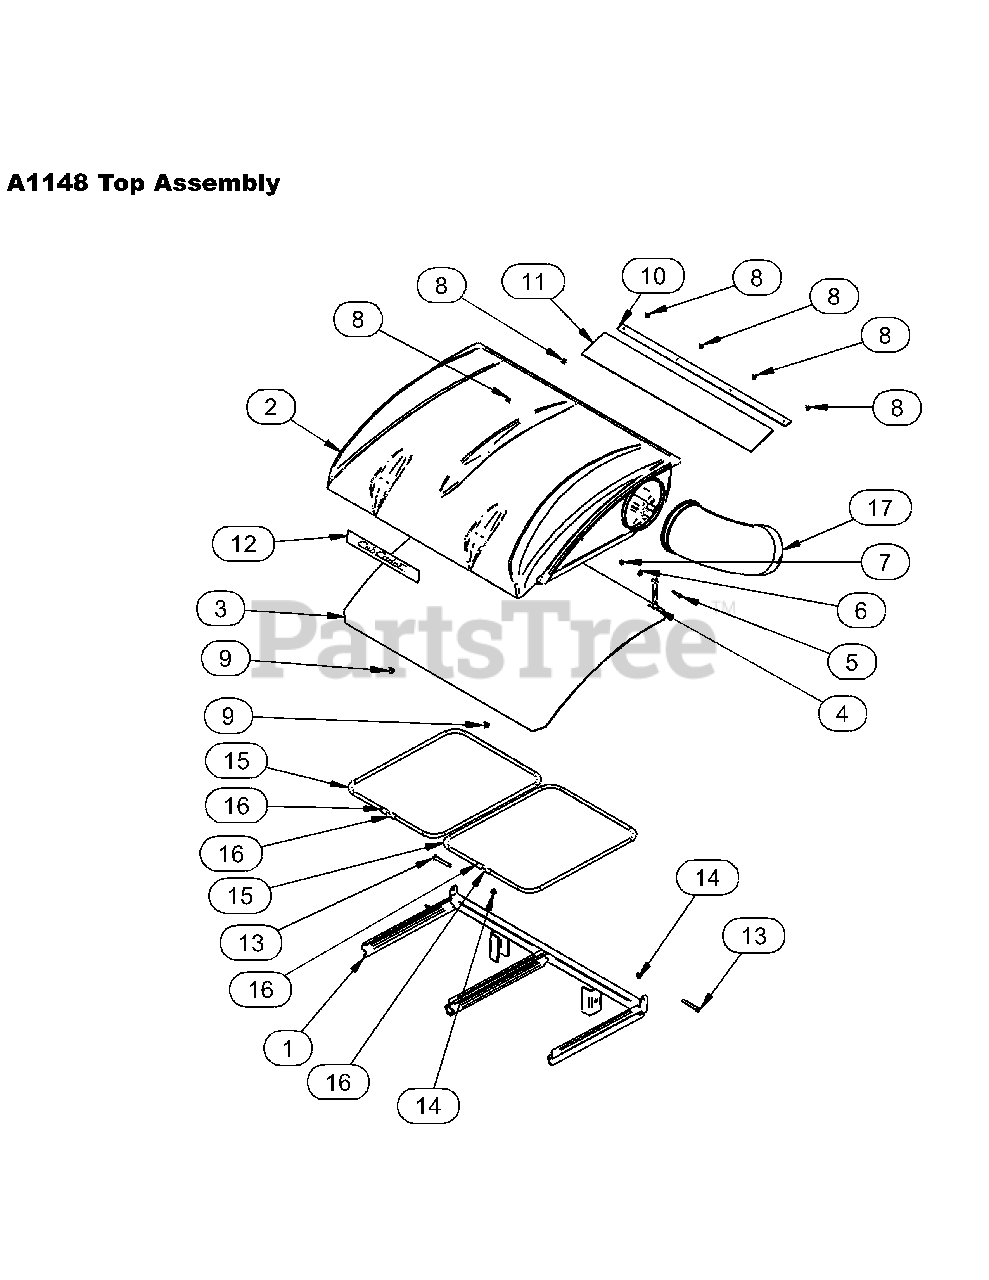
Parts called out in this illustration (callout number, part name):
1	FRAME ASSEMBLY-UPP
2	PRO 2 BAGGER TOP
3	BAGGER TOP SCREEN
4	RUBBER STRAP W/HOO
5	BOLT-1/4-20 X 1-1/
6	WASHER-FLAT
7	NUT-NYLOCK 1/4-20
8	RIVET-PLASTIC 5MM
9	FLAT HEAD FASTENER
10	DUST GUARD BRACE
11	RUBBER SEAL
12	LOGO-CUB CADET
13	BOLT-5/16-18 X 2-1
14	NUT-FLANGE LOCK 5/
16	VINYL CAP
17	P2B INLET/6 INCH/C
A1148	TOP ASSEMBLY-CUB Z
